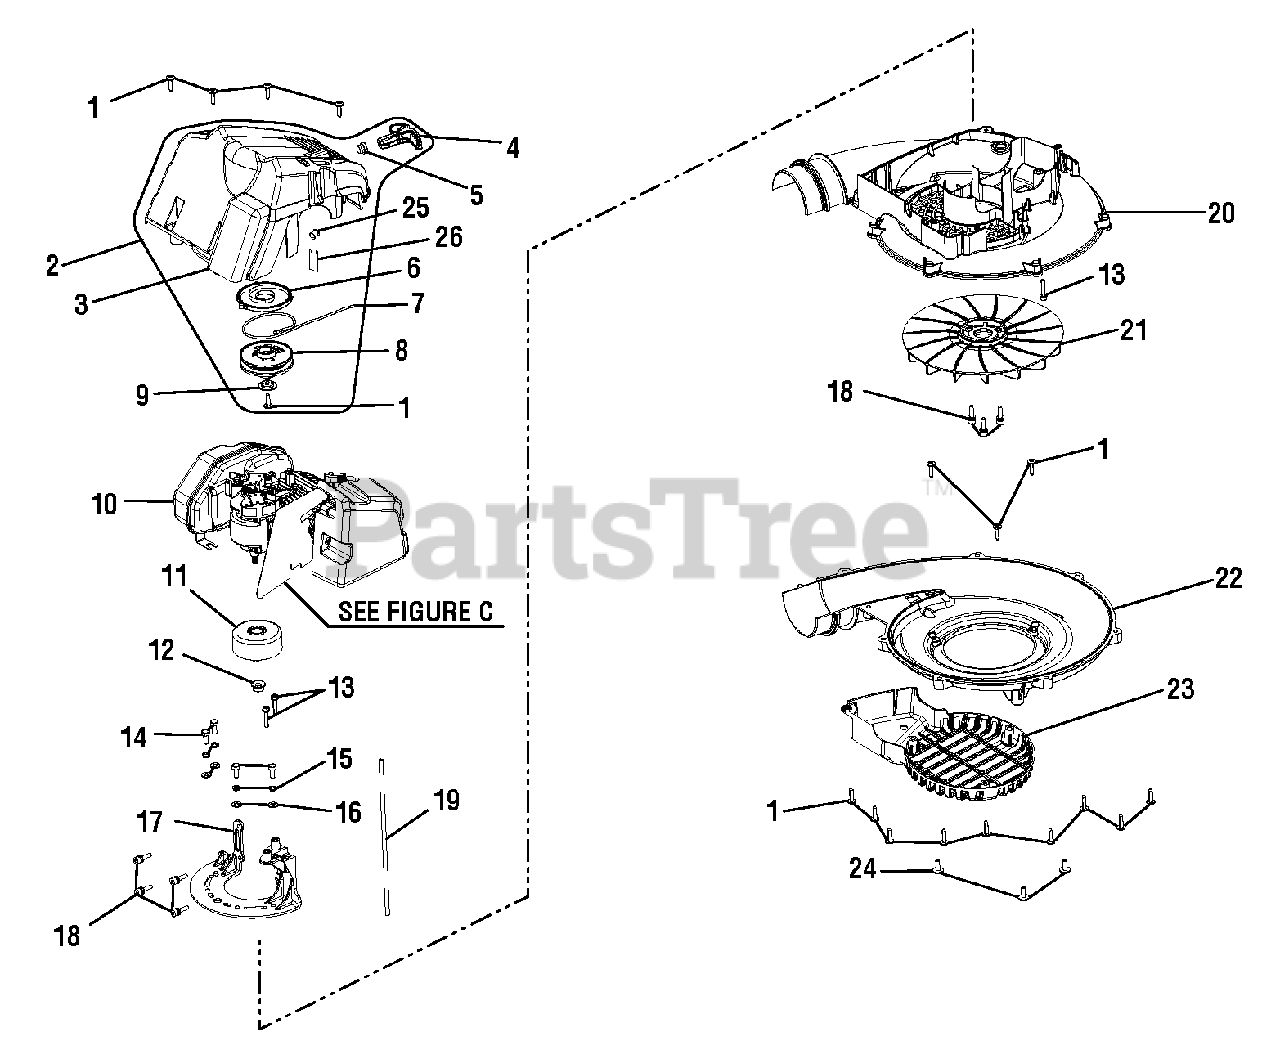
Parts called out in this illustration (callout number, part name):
1	Screw (10-14 x 19 mm, T-25 Torx)
2	Engine Cover w/Starter Assembly
3	Motor Cover
4	Starter Grip
6	Container Spring Assembly
7	Starter Rope
8	Solid Pulley
9	Starter Cap
10	Power Head
12	Lock Nut (M8)
13	Screw (M5 x 25 mm, T-25 Torx)
14	Screw (M6 x 14 mm)
15	Spring Washer (ID6.4 x 1.6t)
16	Washer (OD12.9 x ID6.6 x 1.2t)
17	Engine Mount
18	Screw (M5 x 0.8 in., 20 Torx)
20	Inner Volute
22	Outer Volute
23	Outer Volute Cover
24	Screw (10-14 x 16 mm)
26	Eyelet Support
